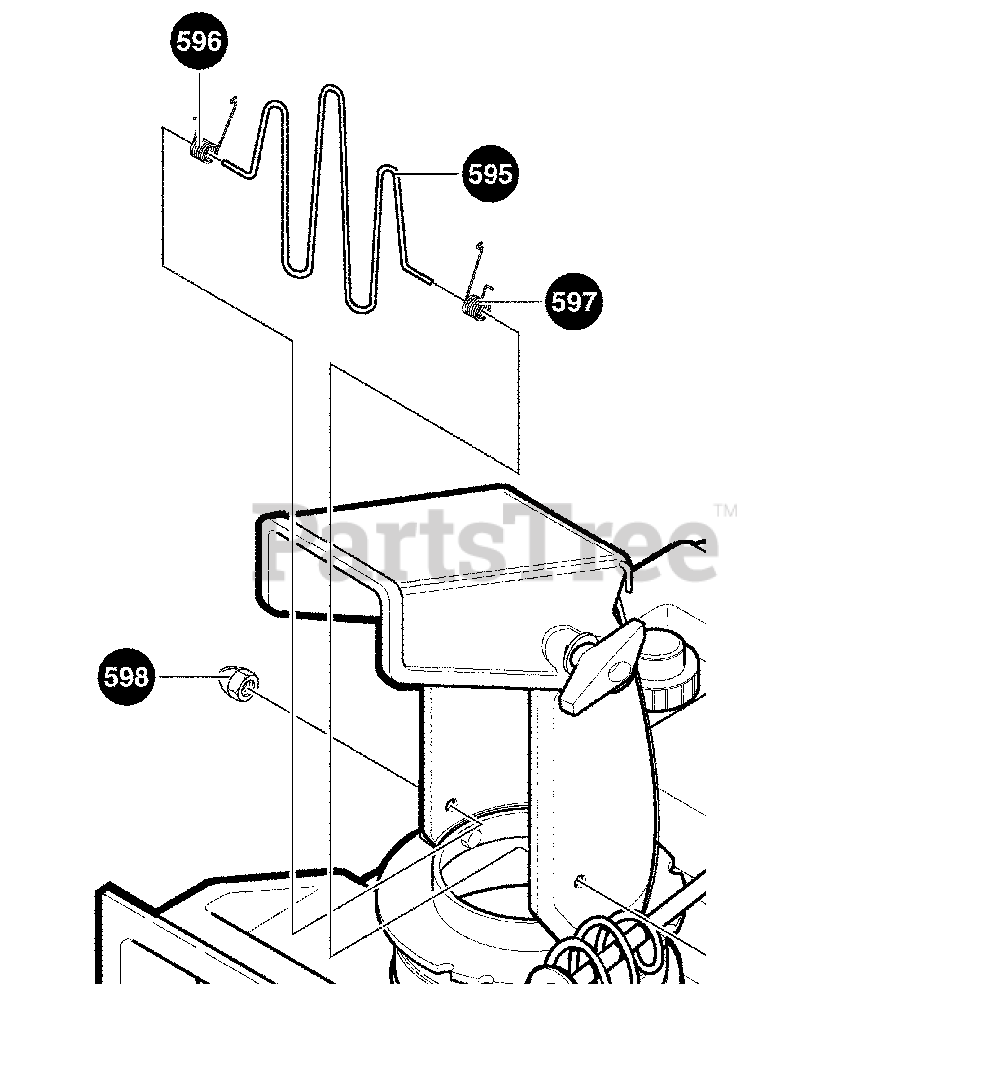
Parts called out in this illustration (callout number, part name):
595	GUARD, WIRE CHUTE
596	SPRING, TORSION
597	SPRING, TORSION
598	NUT, ACORN
